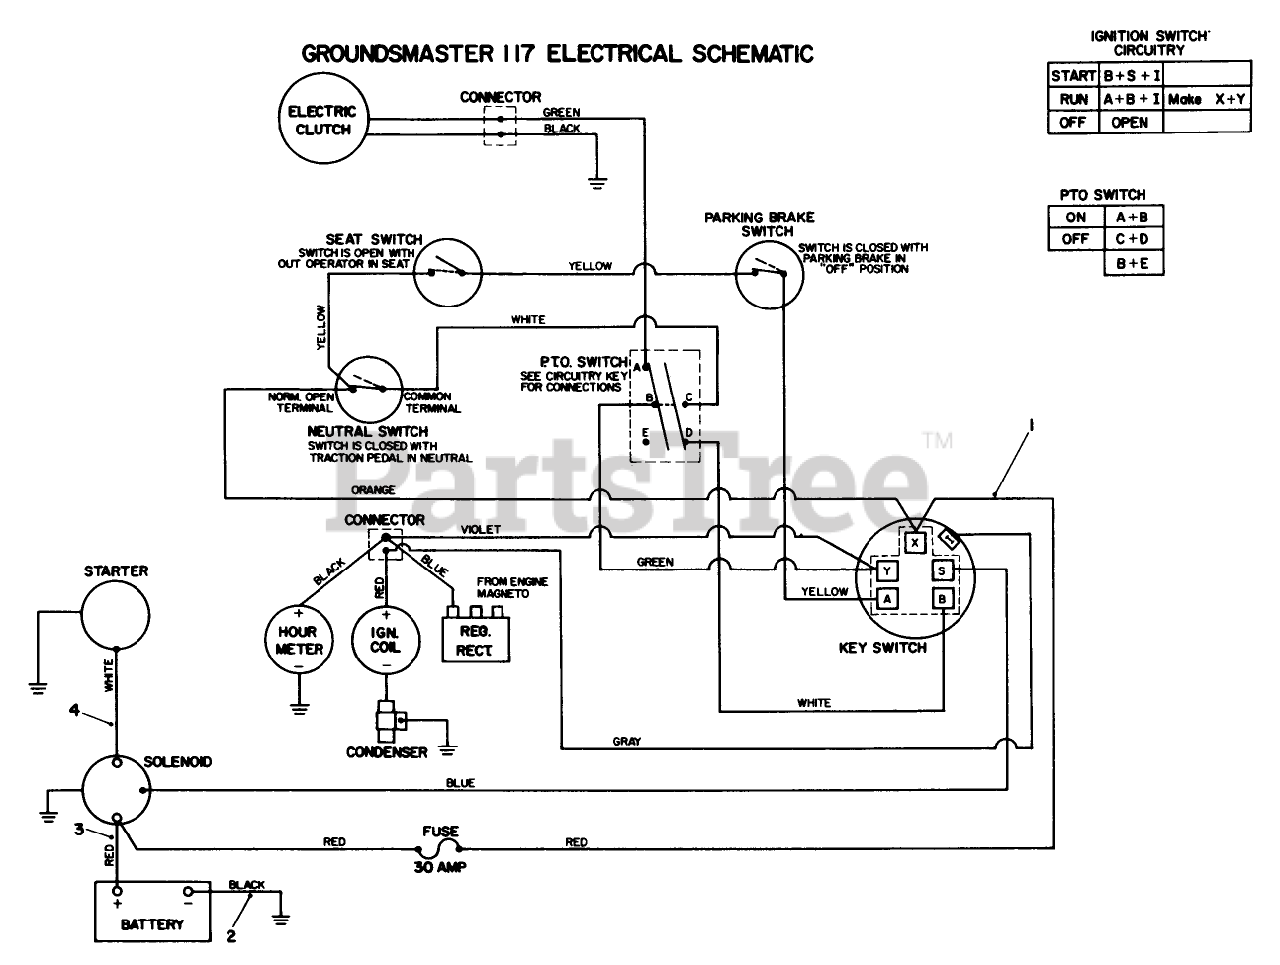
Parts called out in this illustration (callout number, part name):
1	WIRE HARNESS
2	BATTERY/GROUND WIRE
3	WIRE ASM
4	WIRE ASM
